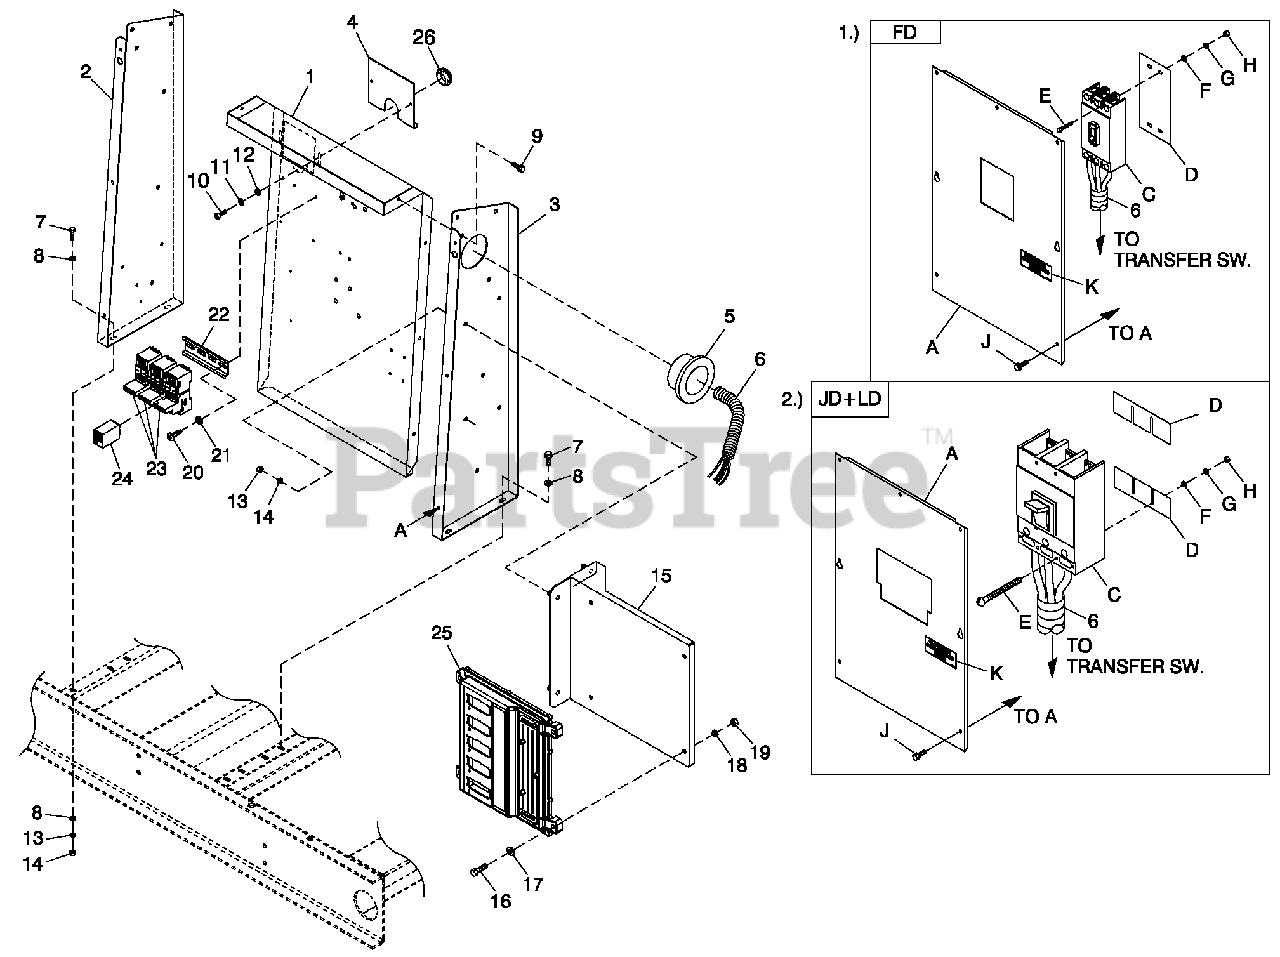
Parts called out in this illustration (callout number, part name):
1	PANEL CB CONN BOX
1	UL CIRCUIT BREAKER (FD)
2	STAND LH CONTROL C5 GRBX
2	UL CIRCUIT BREAKER (JD+LD)
3	STAND RH CONTROL C5
4	PLATE WIRE SNGLGALV
5	BUSHING SNAP SB-2.5-31
6	CONDUIT FLEX 2.0" ID
7	SCREW HHTT $6-1.0 X 16 ZYC
8	WASHER FLAT 1/4-M6 ZINC
9	SCREW THF M6-1 X 16 N WA Z/JS
10	SCREW PHTT M5-0.8 X 16 ZYC
11	WASHER LOCK M5
12	WASHER FLAT M5
13	WASHER LOCK M6-1/4
14	NUT HEX M6 X 1.0 G8 YEL CHR
15	MOUNT POWER MANAGER CPL
16	SCREW HHC M8-1.25X 30 G8.8
17	WASHER FLAT 5/16-M8 ZINC
18	WASHER LOCK M8ZINC
19	NUT HEX M8-1.25 G8 CLEAR ZINC
20	SCREW PHTT M4-0.7 X 10 ZYC
21	WASHER LOCK #8-M4
22	RAIL TERMINAL BLOCK 98MM
23	BASE RELAY DIN MOUNT 4PDT 14P
24	RELAY 4PDT12VDC COIL 5A 250V
25	ASSY PROGRAMMED PMGC
26	GROMMET 1.25 X .25 X .75
A	COVER FD FRM CB
C	CB 0150A3P 600VSFD6 2A
D	INSULATOR CB FD FRAME 30MIL
E	SCREW SH C 1/4-20 X 4 G8.8 NZ
F	WASHER FLAT 1/4-M6 ZINC
G	WASHER LOCK M6-1/4
H	NUT HEX 1/4-20 STEEL
J	SCREW THF M6-1 X 16 N WA Z/JS
K	DECAL CUSTOMER CONNECT INSIDE
A	COVER CIRBRKR JD/LD
C	CB 0300A 3P 600V S JD6 LL
D	INSULATOR CIRCUIT BR. JD/LD
E	SCREW RHM 1/4-20X3
